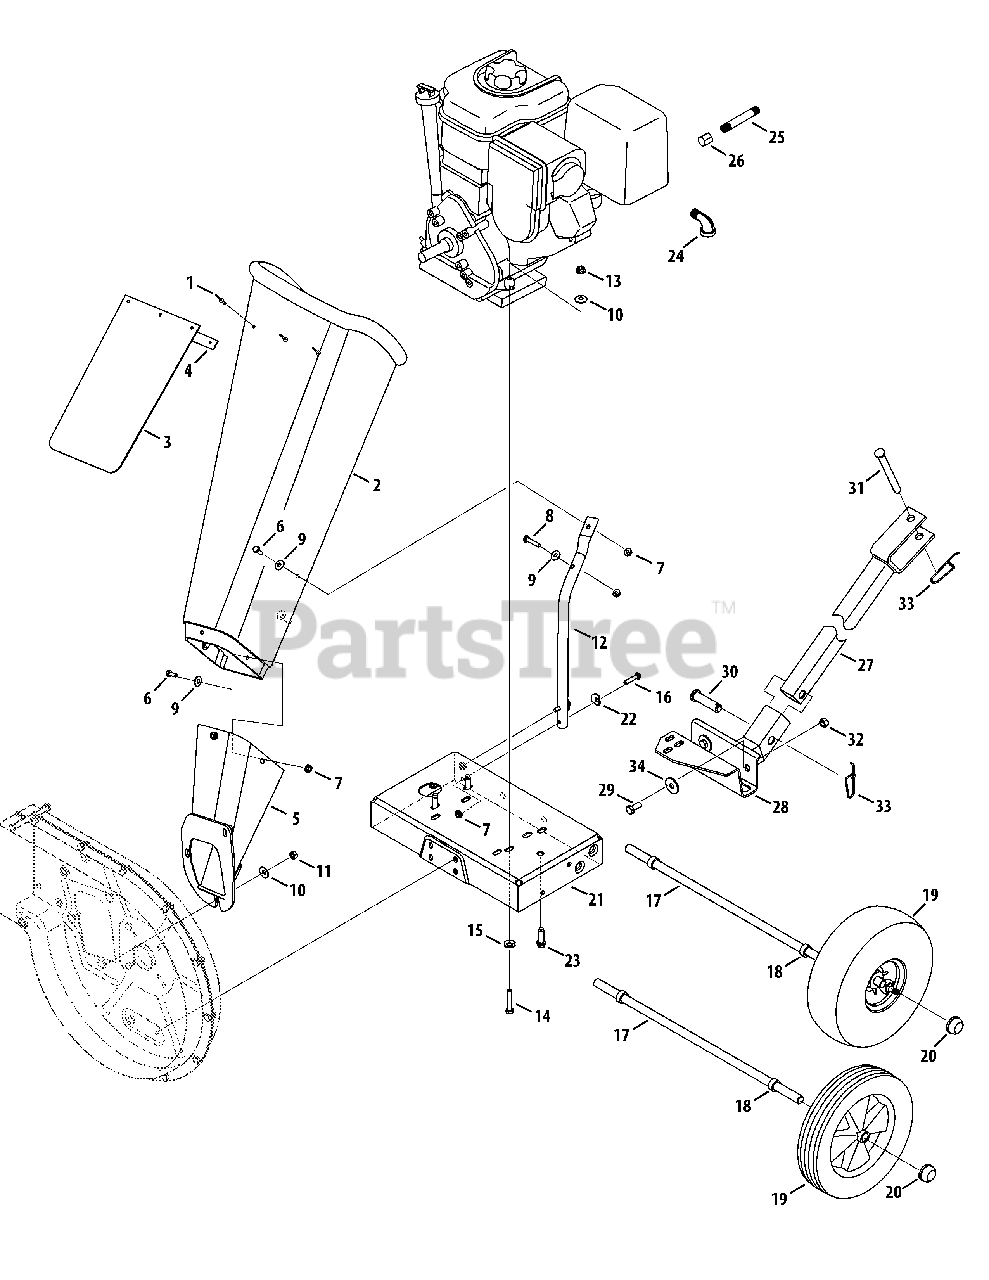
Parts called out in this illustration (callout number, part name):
1	Pop Rivet
2	Chipper Shredder Chute
3	Chute Flap
4	Chute Flap Strip
5	Chipper Chute Assembly
6	Hex Cap Screw 1/4 -20 x.620
7	Hex Lock Nut 1/4-20
8	Hex Cap Screw 1/4-20 x 1.25
9	Flat Washer.28 ID x.74 OD
10	Bell Washer.340 ID x.872 OD
11	Hex Nut 5/16-18
12	Support Brace
13	Hex Lock Nut 5/16-18
14	Hex Cap Screw 5/16-18 x 1.50
15	Bell Washer 5/16 x 1.0
16	Hex Cap Screw, 1/4-20 x 1.250
17	Axle Assembly
18	Spacer
19	Wheel Comp., 10.0 x 2.5 Plastic
20	Push Cap
22	Washer,.320 ID x.93 OD
23	Screw, 3/8-16 x 1.250
24	Elbow Fitting
25	Oil Drain Pipe
26	Oil Drain End Cap
27	Tongue Hitch Mount
28	Base Hitch Mount
29	Hex Cap Screw, 3/8-16 x.88
30	Clevis Pin,.625 x 2.4
31	Clevis Pin,.50 x 4.62
32	Flange Lock Nut, 3/8-16
33	Spring Pin
34	Flat Washer,.411 x 1.25 x 1.0
